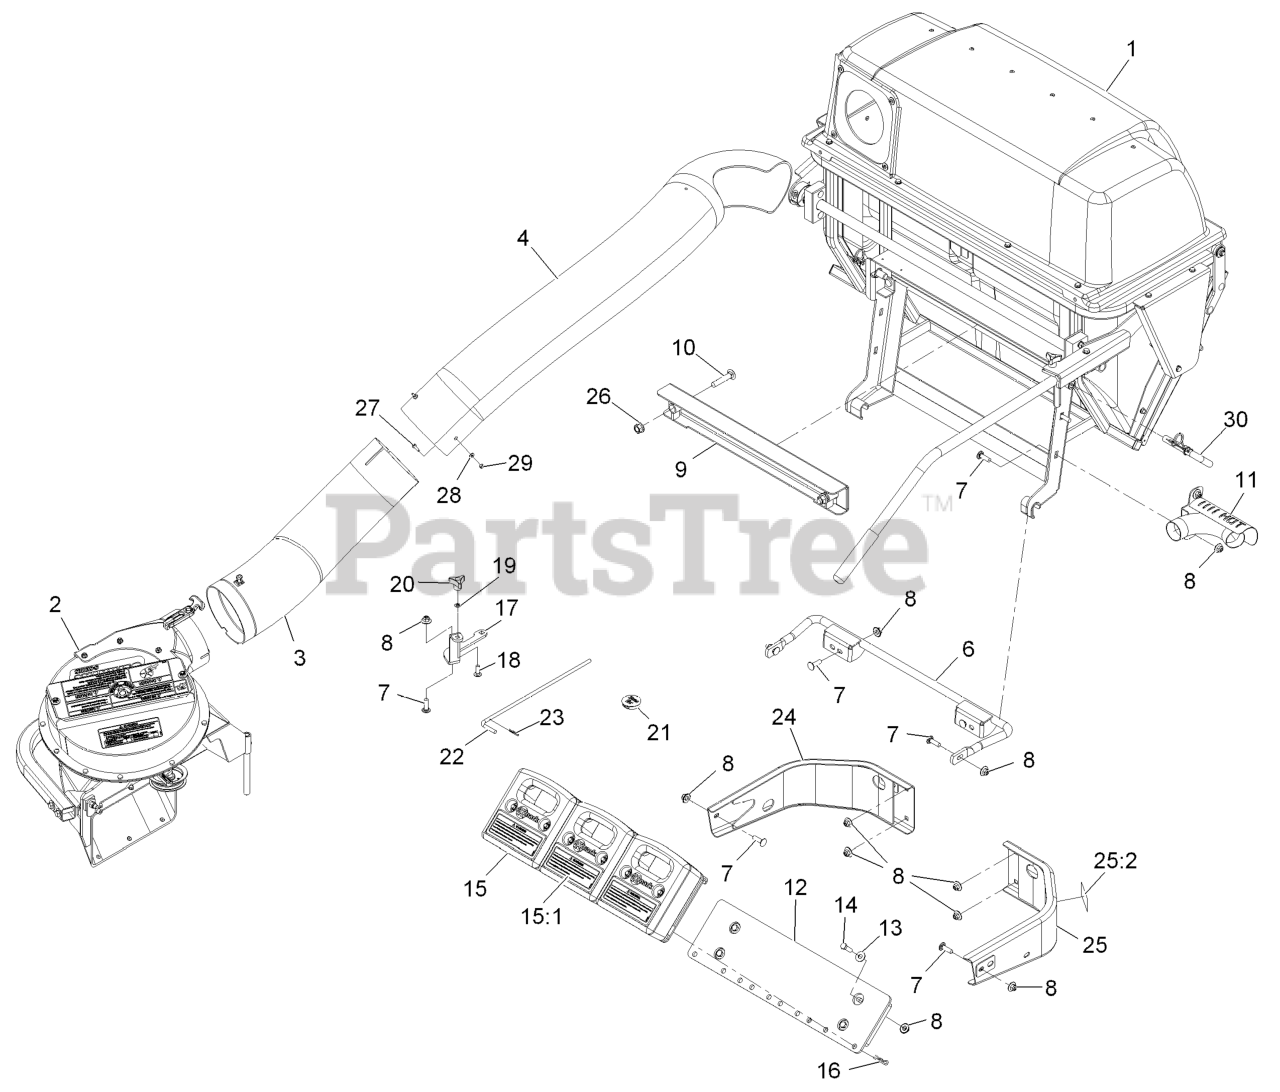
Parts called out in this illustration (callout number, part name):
1	Asm,Hopper Sm Qds
2	ASM, BLOWER SMALL - SVC O
3	LOWER TUBE ASM
4	TUBE-UPPER
6	MOUNT-BAGGER, LOWER
7	Bolt-Carriage 3/8-16 X 1 1/4
8	Nut-Nyloc 3/8-16 Flg
9	MOUNT-BAGGER, UPPER
10	SCREW-CARR
11	EXHAUST DIVERTER ASM
12	WLD, MOUNT TOEBOARD WEIGH
13	WASHER-FLAT
14	SCREW-HH
15	ASM,CAST WEIGHT
15:1	DECAL,WEIGHT
16	PIN-HAIR
17	BRACKET, SMALL UV BELT CO
18	BOLT-CARR
19	RING-RETAINING, BOLT
20	KNOB-3 PRONG
21	PLUG, BLACK NYLON 1.75
22	PIN,CHUTE PIVOT
23	PIN-COTTER
24	BUMPER-RH
25	LH BUMPER ASM
25:2	DECAL-CAUTION
26	Nut-Lock 1/2-13
27	SCREW-HWH
28	WASHER-FLAT
29	NUT-LOCK, NI
30	PIN-MOUNT, BAGGER
